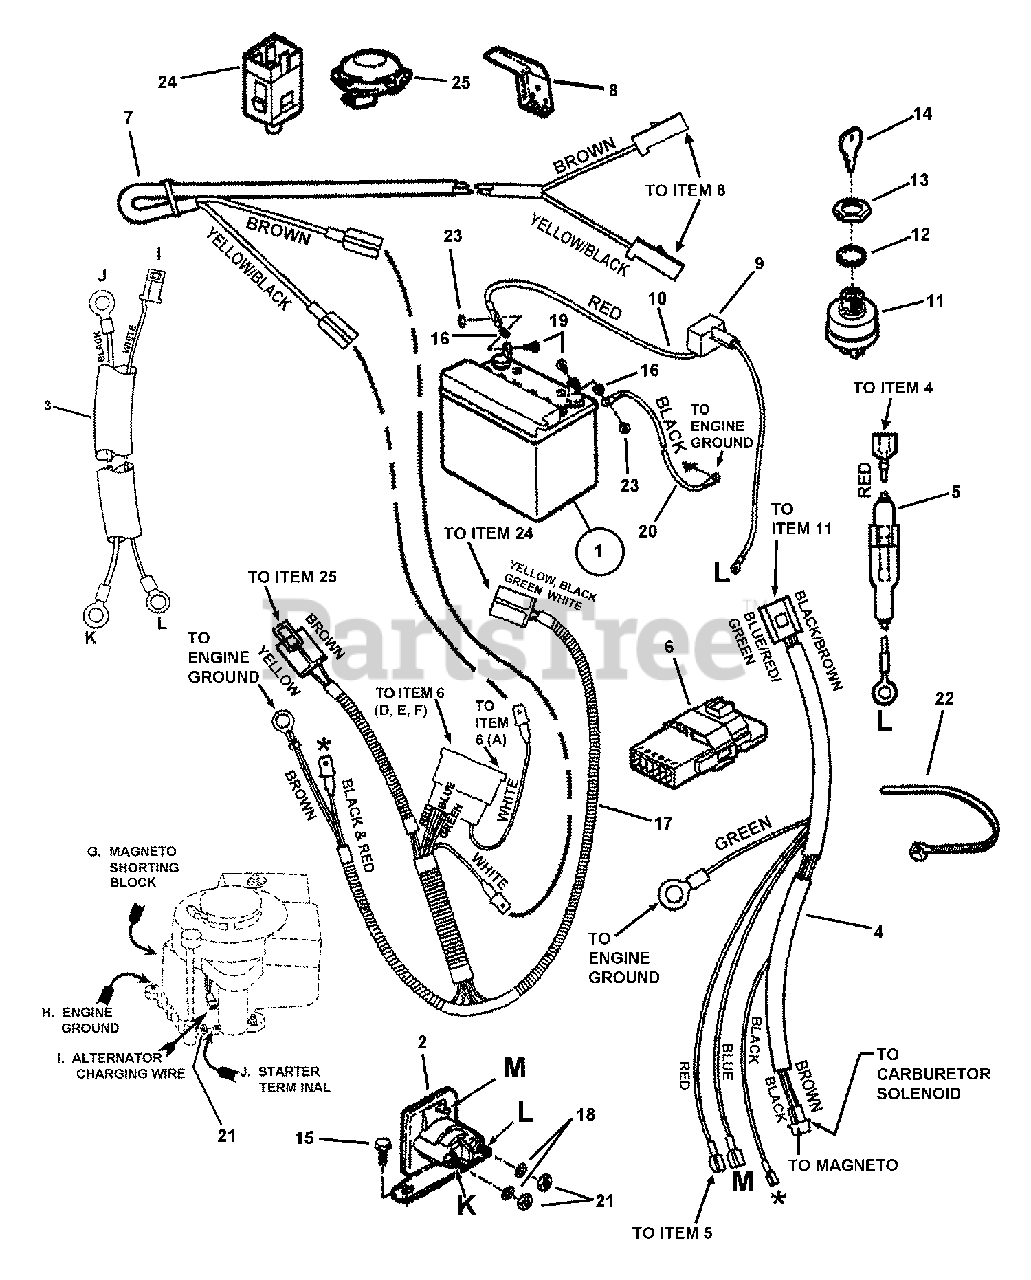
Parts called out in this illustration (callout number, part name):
1	KIT, Battery, 12 Volt, 220CCA, Dry Charge
2	SOLENOID, Super-Trombetta
3	HARNESS, Starter Wiring (Briggs, AC)
4	HARNESS, Ignition Wiring
5	HOLDER, Fuse (Includes Fuse)
6	INTERLOCK MODULE, Briggs
7	HARNESS (Deck Interlock Wiring)
8	SWITCH, Deck Interlock (NO)
9	COVER, Battery Cable
10	WIRE, Positive (Red, 17 long)
11	SWITCH, Ignition-Afterfire Solenoid
12	WASHER, 5/8 Internal Tooth Lock
13	NUT, 5/8-32 Hex
14	IGNITION KEY, Pair
14	KEYS, Blister Pk (KIDS+MWRS DON'T MIX) English/French (set of two, one coated)
15	HHCS, 1/4-20 X .500, GR5 Zinc/Clear Hex Washer HD Taptite
16	RETAINER, 1/4 Bolt
17	HARNESS WIRE, Operator Presence Control (OPC)
18	WASHER,1/4 Internal Tooth Lock
19	HHCS, 1/4-20 X 0.625, GR5 Zinc/Clear
20	WIRE, Negative, Black (15 long)
21	NUT, 1/4-20, Zinc/Clear (attaches to starter terminal)
22	CABLE TIE, 7"
23	NUT, 1/4-20 Hex Center Lock, GR 5 or B
24	SWITCH, Operator Presence Control (OPC) Traction (NC/NO)
25	SWITCH, Seat (Normally Closed)
